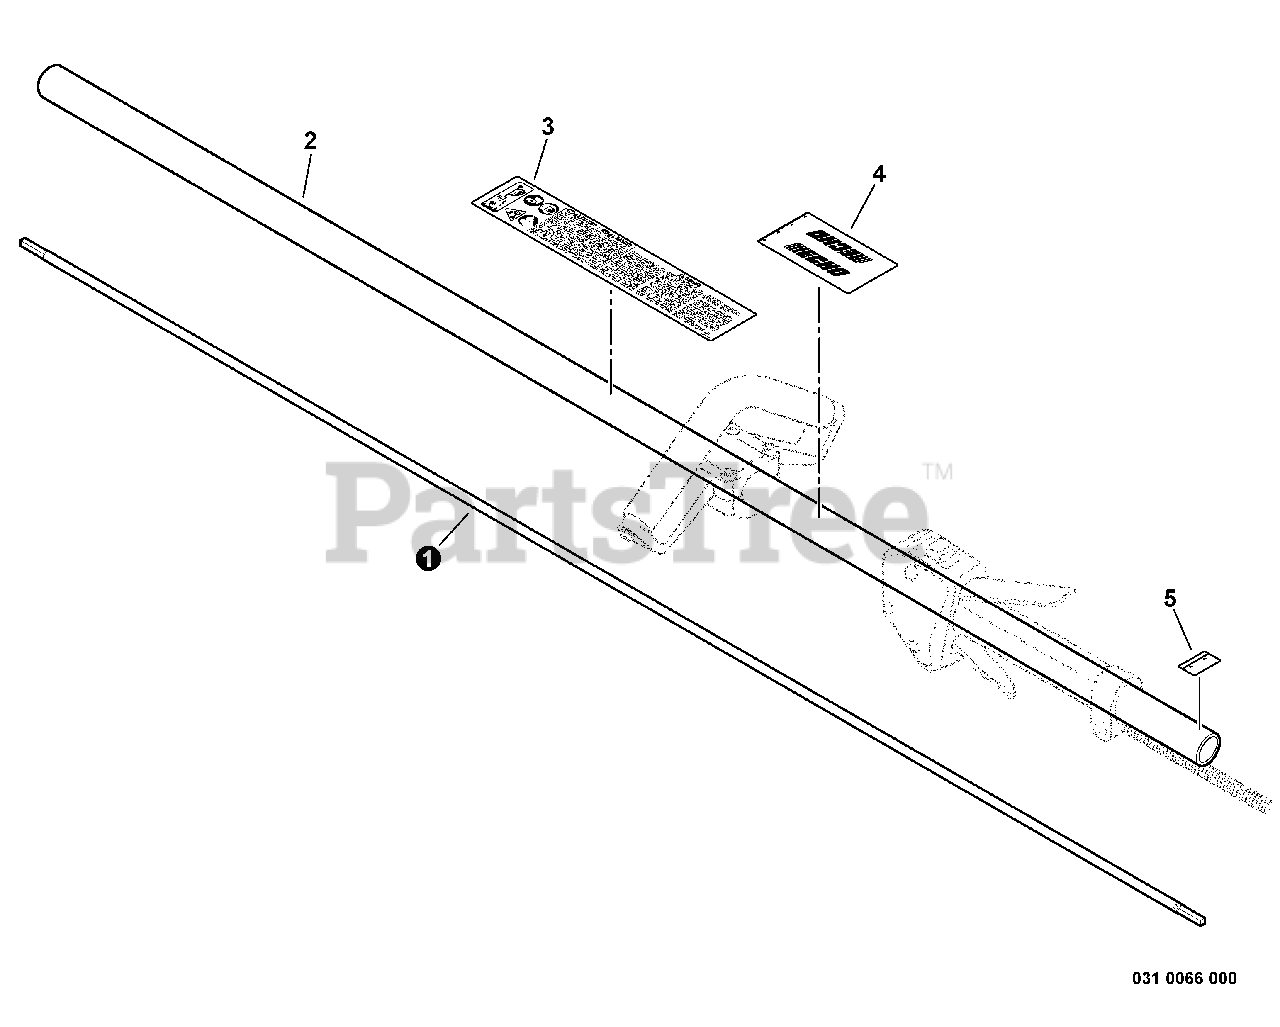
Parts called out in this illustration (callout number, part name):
1	DRIVESHAFT - SOLID
2	MAIN PIPE ASSY
3	LABEL - CAUTION -- SPANISH
4	LABEL - HANDLE LOCATION
5	LABEL - ALIGNMENT
